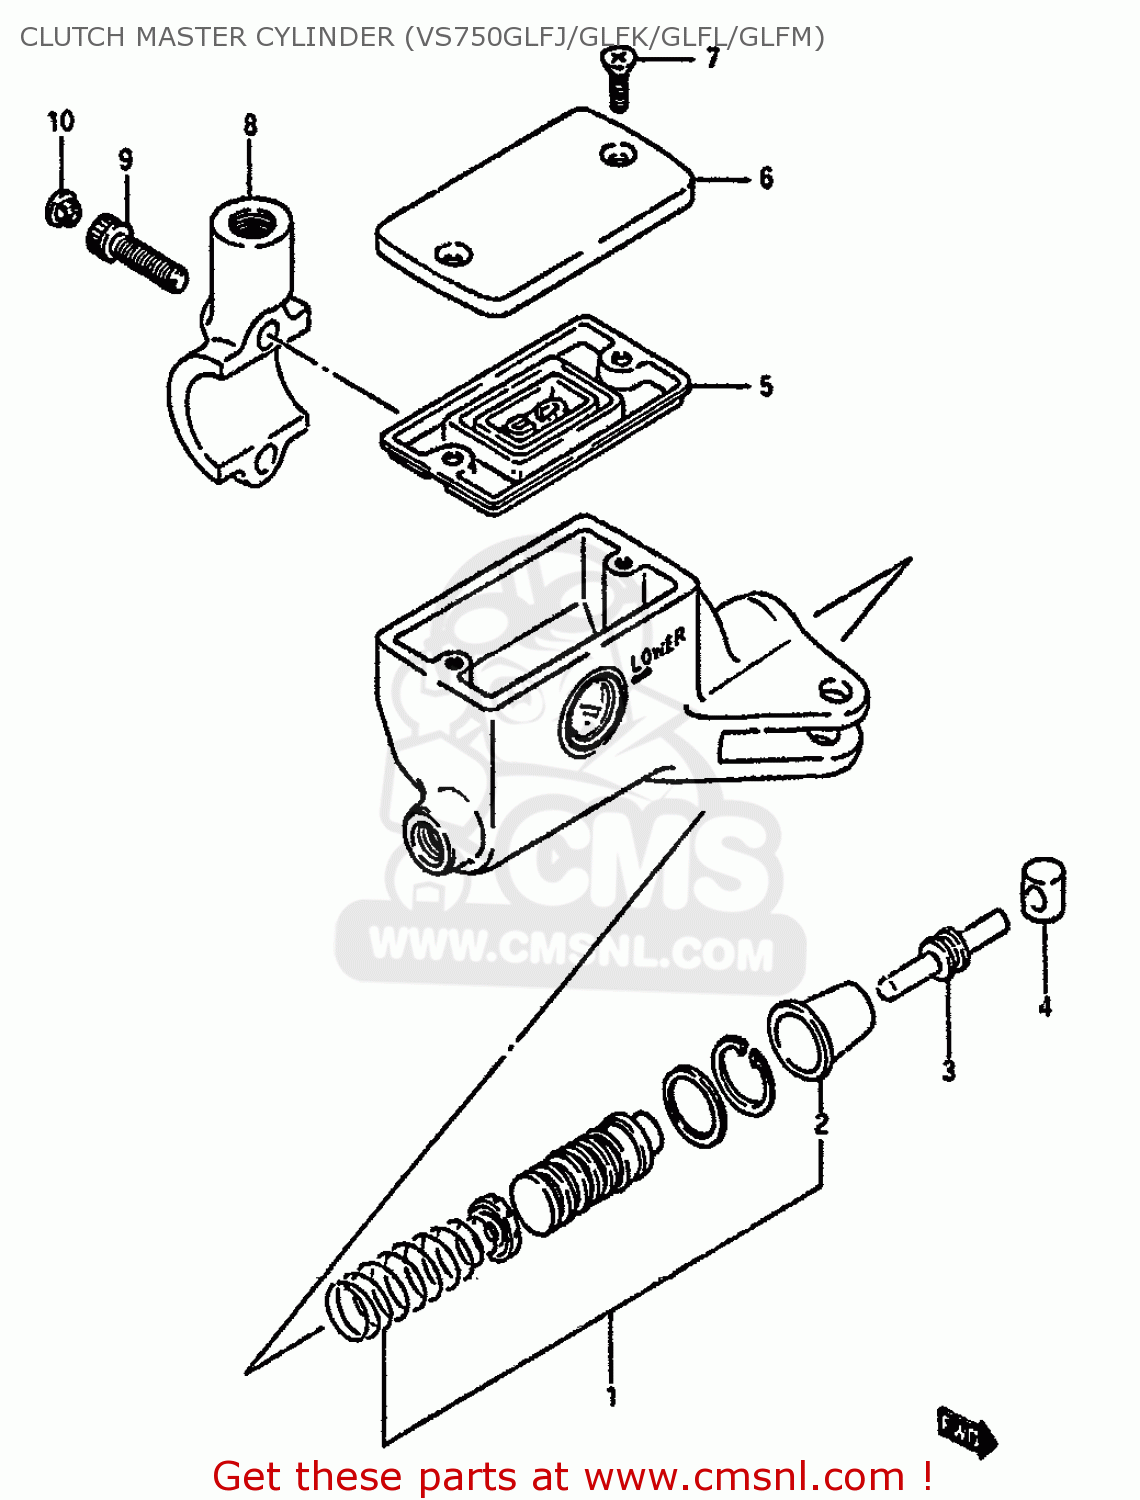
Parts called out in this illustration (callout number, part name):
1	PISTON & CUP SET
2	BOOT
3	PUSH ROD
4	BUSH
5	6-1
6	CAP
7	SCREW,RESERVOIR CAP
8	HOLDER
9	BOLT
10	CAP(OD:10)
